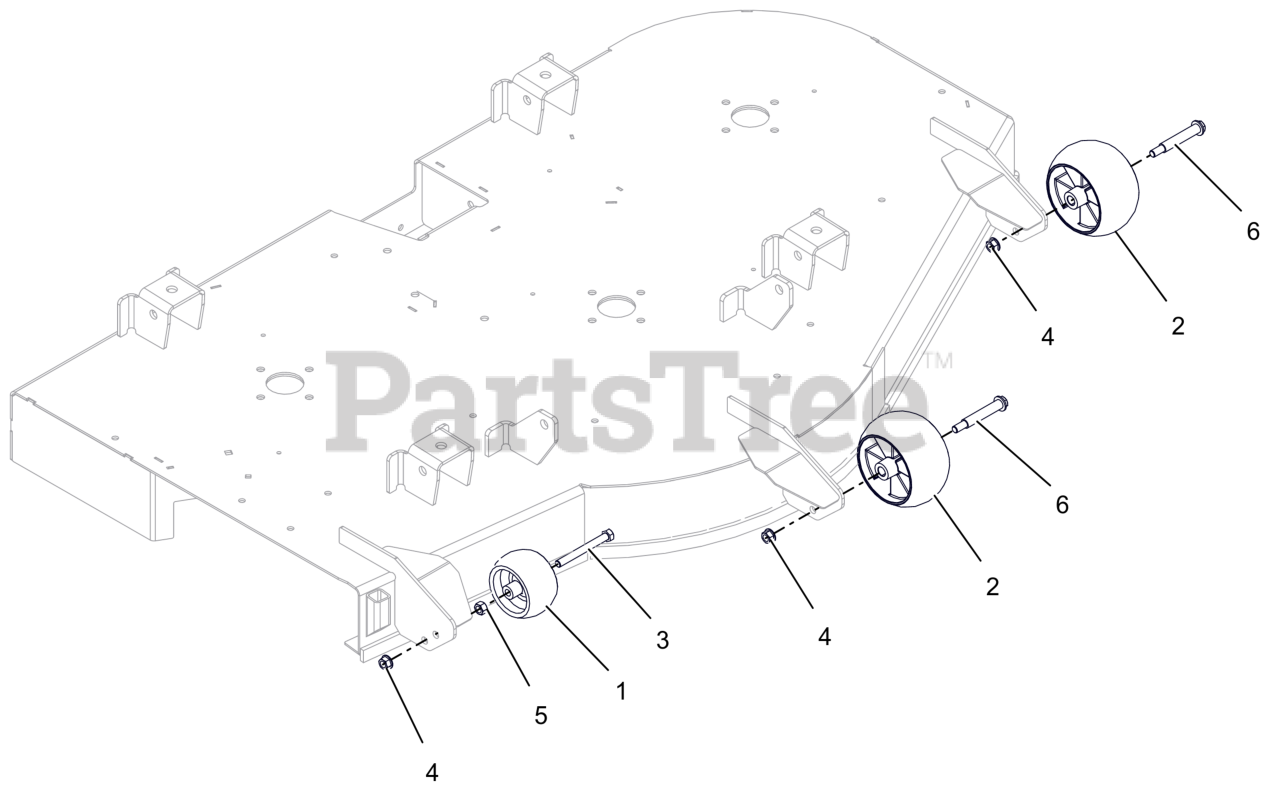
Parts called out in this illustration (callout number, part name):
2	ANTI-SCALP WHEEL - 5X OS
3	BLT, HEX .38-16X3.50 G5 ZCC
4	NUT-LK-CTR-FLG .375-16 GF ZCC
5	NUT-STD .375-16 G2 ZCC
6	BLT-SHLDR .38-16X2.50 HWH G5
